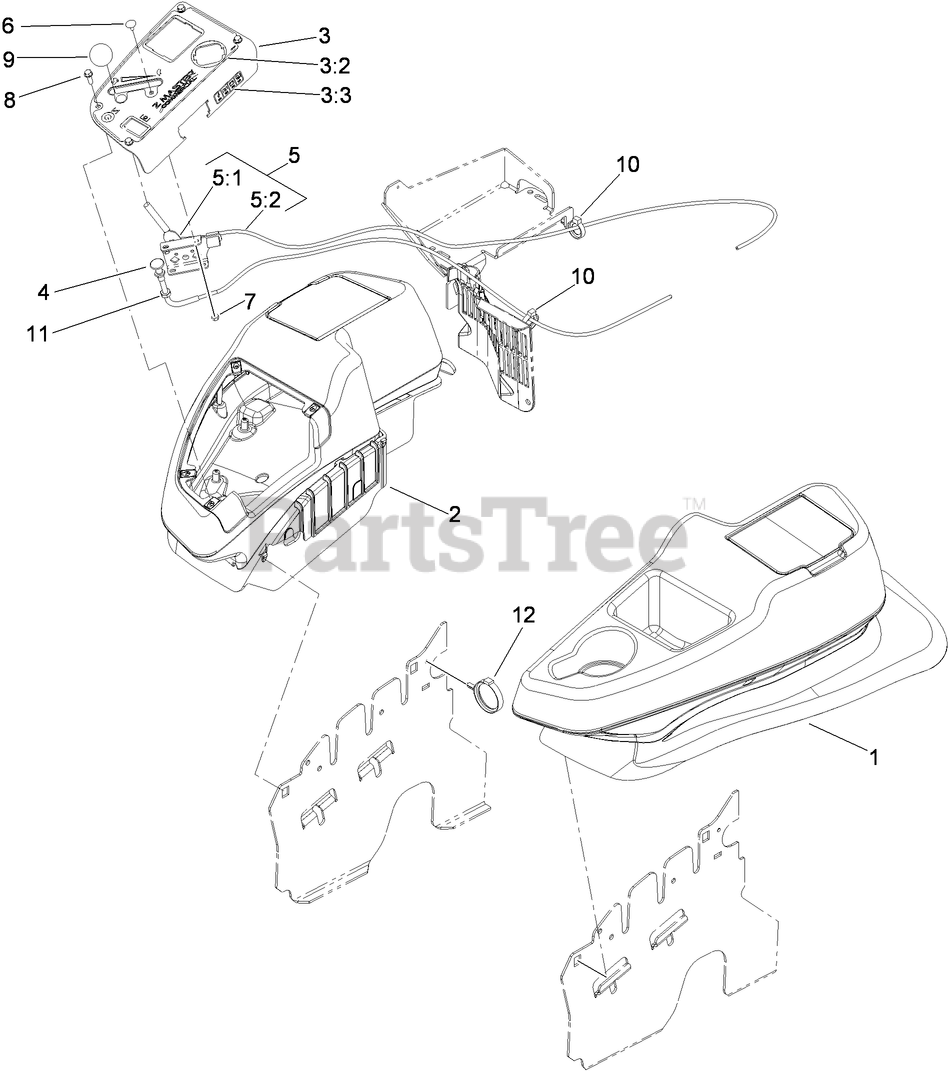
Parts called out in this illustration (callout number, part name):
1	LH CONSOLE ASM
2	RH CONSOLE ASM
3	CONTROL PANEL ASM
3:2	DECAL-PANEL, CONTROL
3:3	DECAL-FUSES
4	CONTROL-CHOKE
5	THROTTLE CONTROL ASM
5:1	LEVER-THROTTLE
5:2	CABLE-THROTTLE
6	BOLT-CARR
7	NUT-LOCK, NI
8	SCREW-HWH
9	KNOB-BALL
10	CLAMP-HOSE
11	NUT-HJ
12	CLAMP-HARNESS
